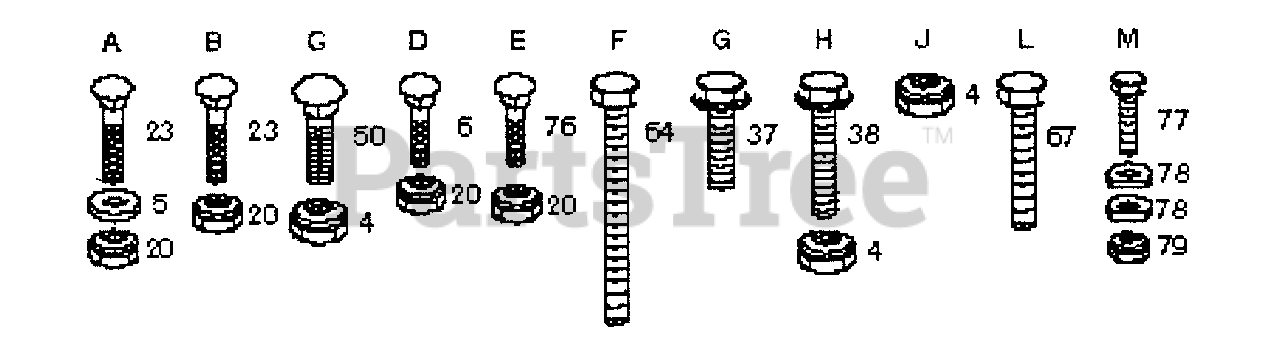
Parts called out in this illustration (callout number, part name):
4	Locknut 3/8 - 16
5	Washer 11/32 x 3/4 x 16 Ga.
6	Bolt, Carr. 5/16-18 x 5/8
20	Locknut 5/16 - 18
23	Bolt, Carriage 5/16 - 18 x 3/4
37	Screw, Hex Washer Hd. 3/8 - 16 x 7/8
38	Screw, Hex Washer Hd. 3/8 - 16 x 1-1/4
50	Bolt, Carriage 3/8 - 16 x 3/4
64	Bolt 3/8 - 16 x 5 - 1/2
67	Bolt, Carriage 3/8 - 16 x 1-1/4
76	Bolt, Carriage 5/16 - 18 x 3/4
77	Bolt Hex 1/4 x 20 x 3/4
78	Washer, Special
79	Locknut 1/4-20
